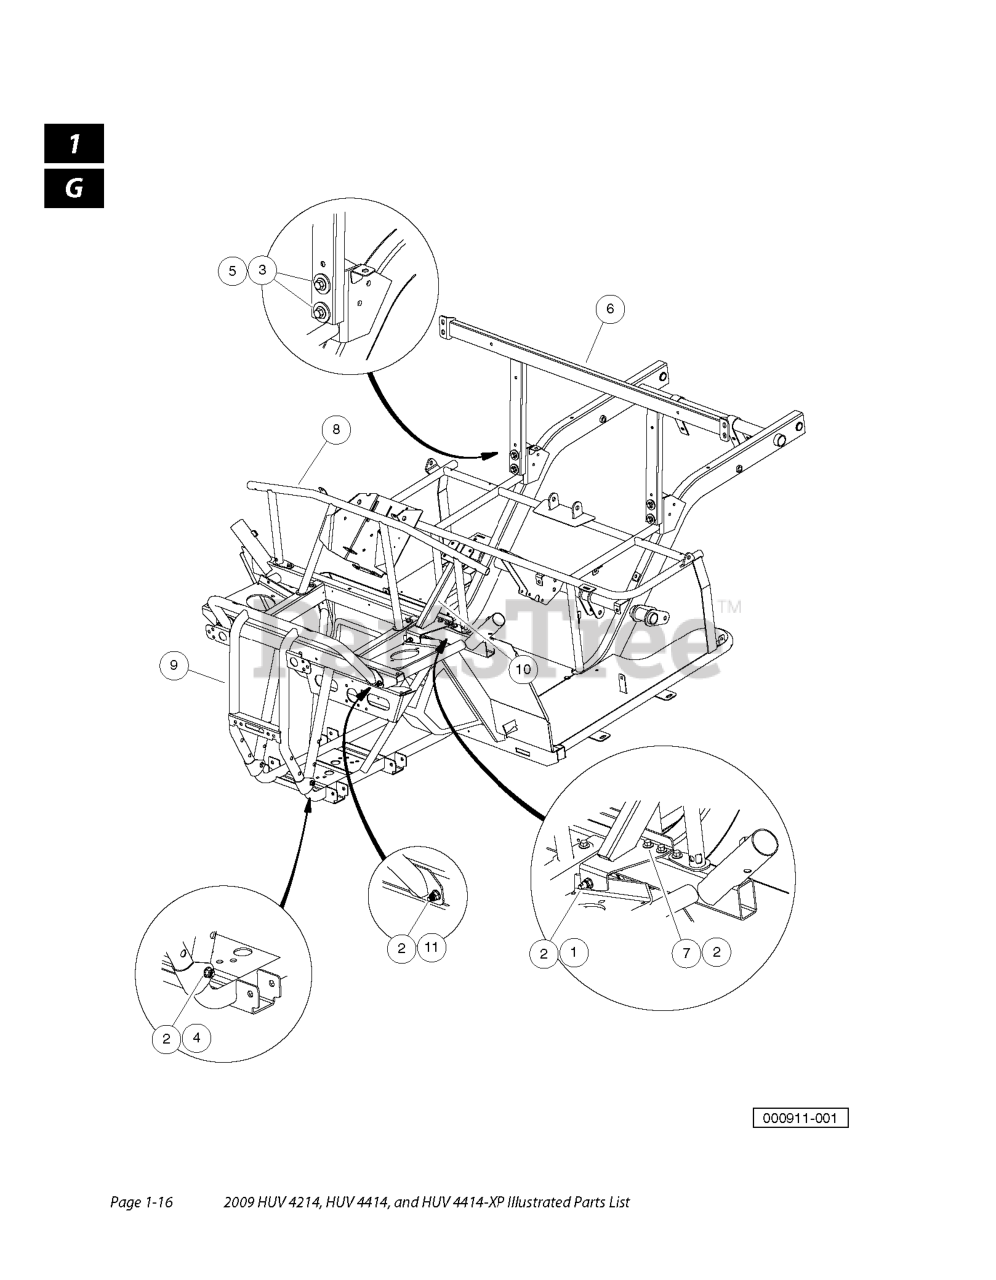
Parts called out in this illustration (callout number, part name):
1	BOLT - FLANGED HD, M8 X 30.0
2	NUT FLG, M8 X 1.25 MECH DEF
3	WASHER HARD, M10
4	BOLT FLG, M8X1.25 X 50 LOCTITE
5	BOLT, FLG, M10X1.5X55, PATCH
6	WELDMENT,MTG,SEAT BACK
7	BOLT, FLG, M8 X 1.25 X 80
11	BOLT, FLG, M8 X X 60
